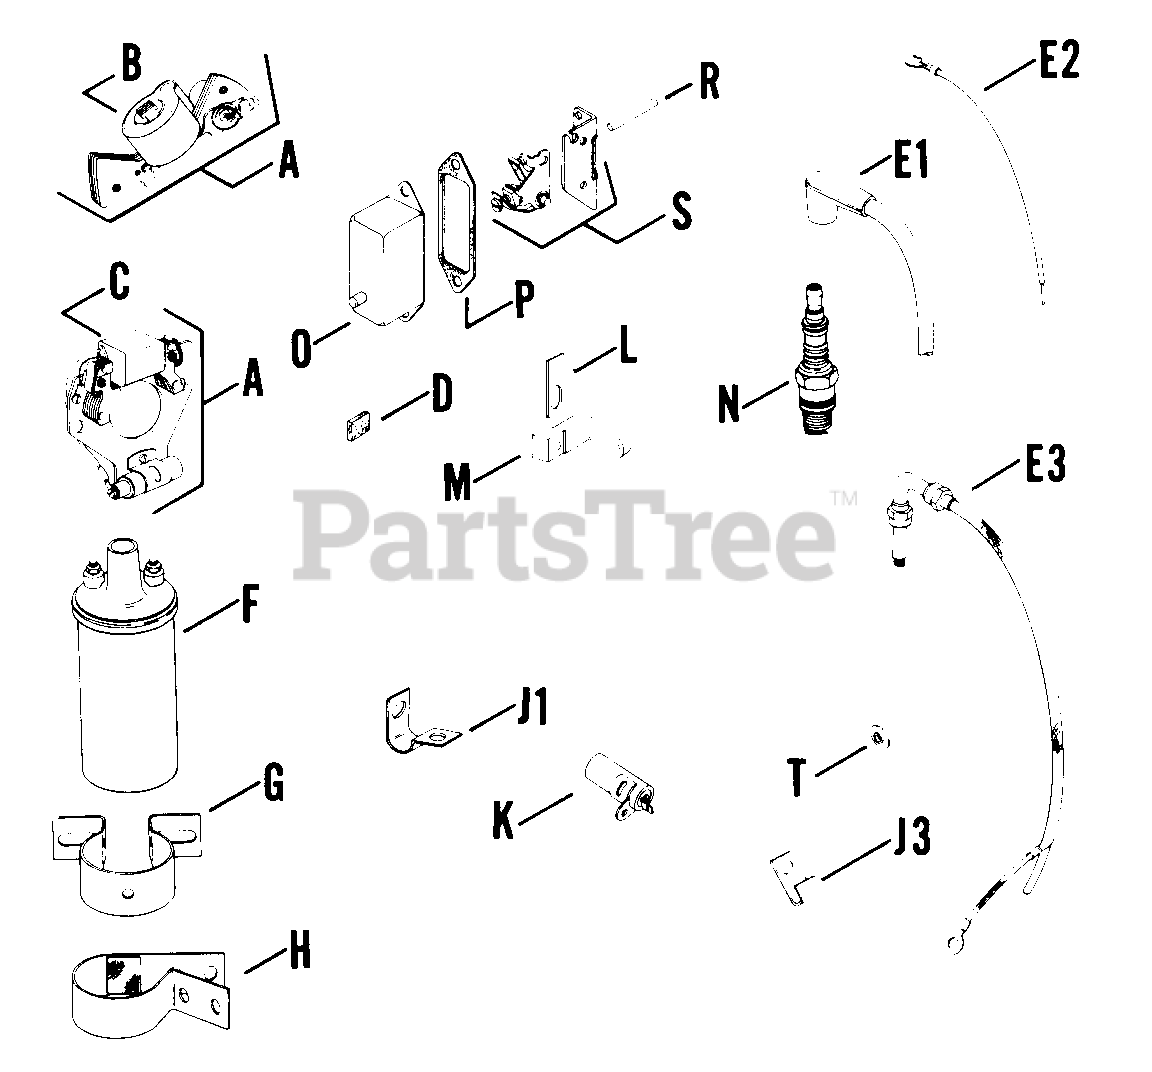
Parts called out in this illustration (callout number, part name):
A	STATOR
B	COIL - DISCONTINUED
E1	LEAD - USE 25 348 01
J1	CLIP - USE 210281
K	CONDENSER
N	SPARK PLUG - USE 41 132 06
O	COVER - DISCONTINUED
P	GASKET - USE 52 041 11
R	ROD
S	BREAKER - USE 47 150 03
